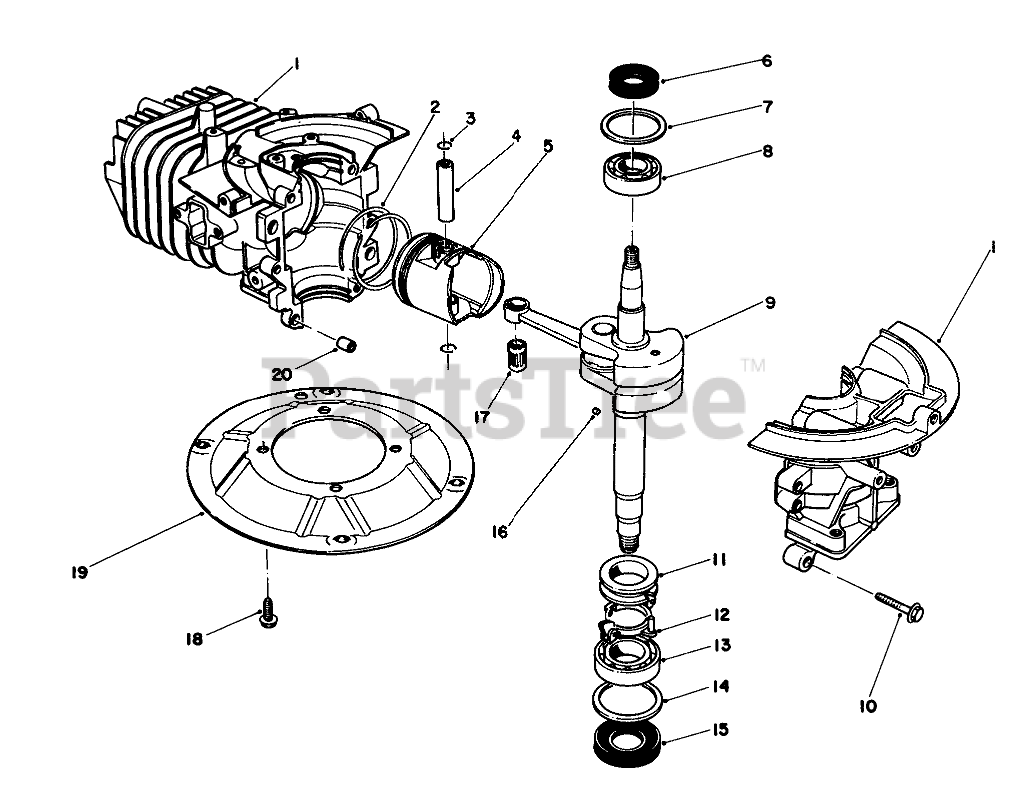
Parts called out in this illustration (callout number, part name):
1	Crankcase/Cylinder Assembly (used on units with Serial No. 6000101-6002200)
1	Crankcase/Cylinder Assembly (used on units with Serial No. 6002201 & up)
2	RING SET
4	PIN-PISTON
5	Piston
6	OIL SEAL
7	WASHER-UPPER
8	BEARING-UPPER
9	Crankshaft/Connecting Rod Assembly
10	Bolt (30mm Lg.)
11	SPACER
12	BRACKET
13	LOWER BRG
14	WASHER-LOWER
15	SEAL-OIL
17	BEARING
19	PLATE-MOUNTING
